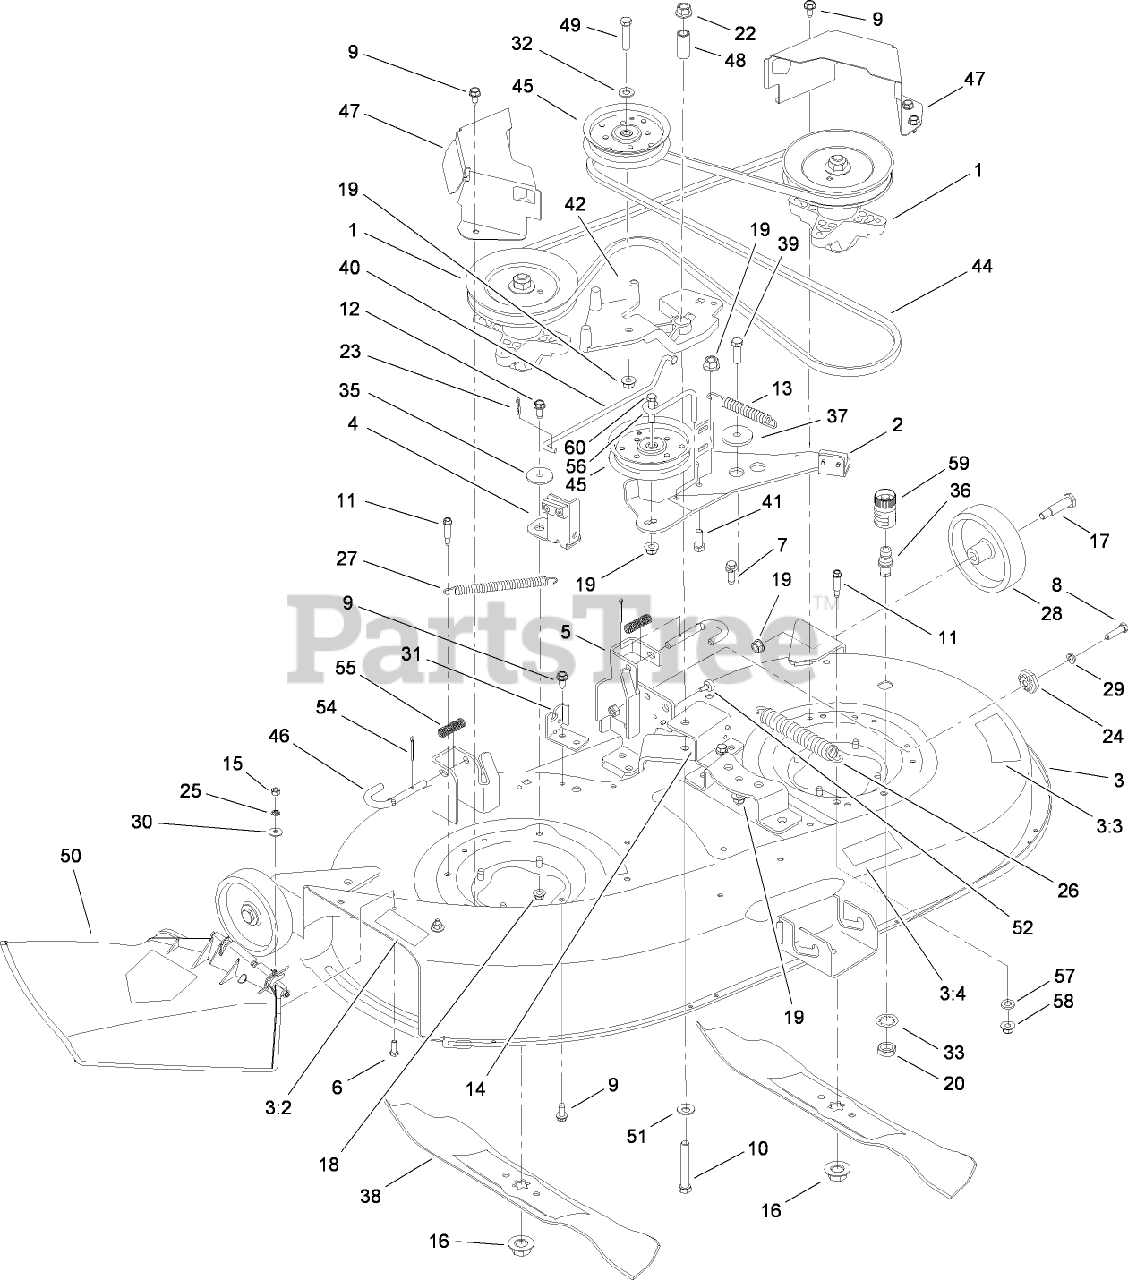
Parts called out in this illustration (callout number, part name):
1	SPINDLE ASM
2	DECK BRAKE ASM
3	DECK AND DECAL ASM
3:2	DECAL-DANGER
3:3	DECAL-DANGER
3:4	DECAL-ROUTING, BELT
4	BRAKE ASM
5	LH HANGER BRACKET ASM
6	SCREW-HH
7	SCREW-HWHTF
8	SCREW-HH
9	SCREW-TAP
10	SCREW-HH
11	SCREW-HWH
12	SCREW-HH
13	SPRING-EXTENSION
14	SUPPORT-BRACKET, PIVOT
15	NUT-HEX
16	NUT-LOCK, FLANGE
17	BOLT-SHOULDER
18	NUT-LOCK, FLANGE
19	NUT-LOCK, FLANGE
20	NUT-HEX
22	NUT-LOCK, FLANGE
23	PIN-COTTER
24	GEAR-ADJUSTMENT, DECK
25	RETAINER-BOLT
26	SPRING-EXTENSION
27	SPRING-EXTENSION
28	WHEEL-DECK, REAR
29	WASHER-LOCK
30	WASHER-SPRING
32	WASHER-FLAT
33	WASHER-LOCK
35	SPACER-SHOULDER
36	NOZZLE-WATER, DECK
37	SPACER-SHOULDER
39	SCREW-HH
40	ROD-BRAKE
41	SCREW-HH
42	BRACKET-IDLER
44	BELT-V TYPE
45	PULLEY-IDLER
46	PIN-HANDLE, DECK RELEASE
47	COVER-BELT
48	SPACER
49	SCREW-HH
50	DISCHARGE CHUTE ASM
51	WASHER-FLAT
52	BUMPER
54	PIN-COTTER
55	SPRING-COMPRESSION
56	ROD-KEEPER, BELT
57	WASHER-FLAT
58	NUT-LOCK, FLANGE
59	ADAPTER-NOZZLE, WATER
60	SCREW-HH
